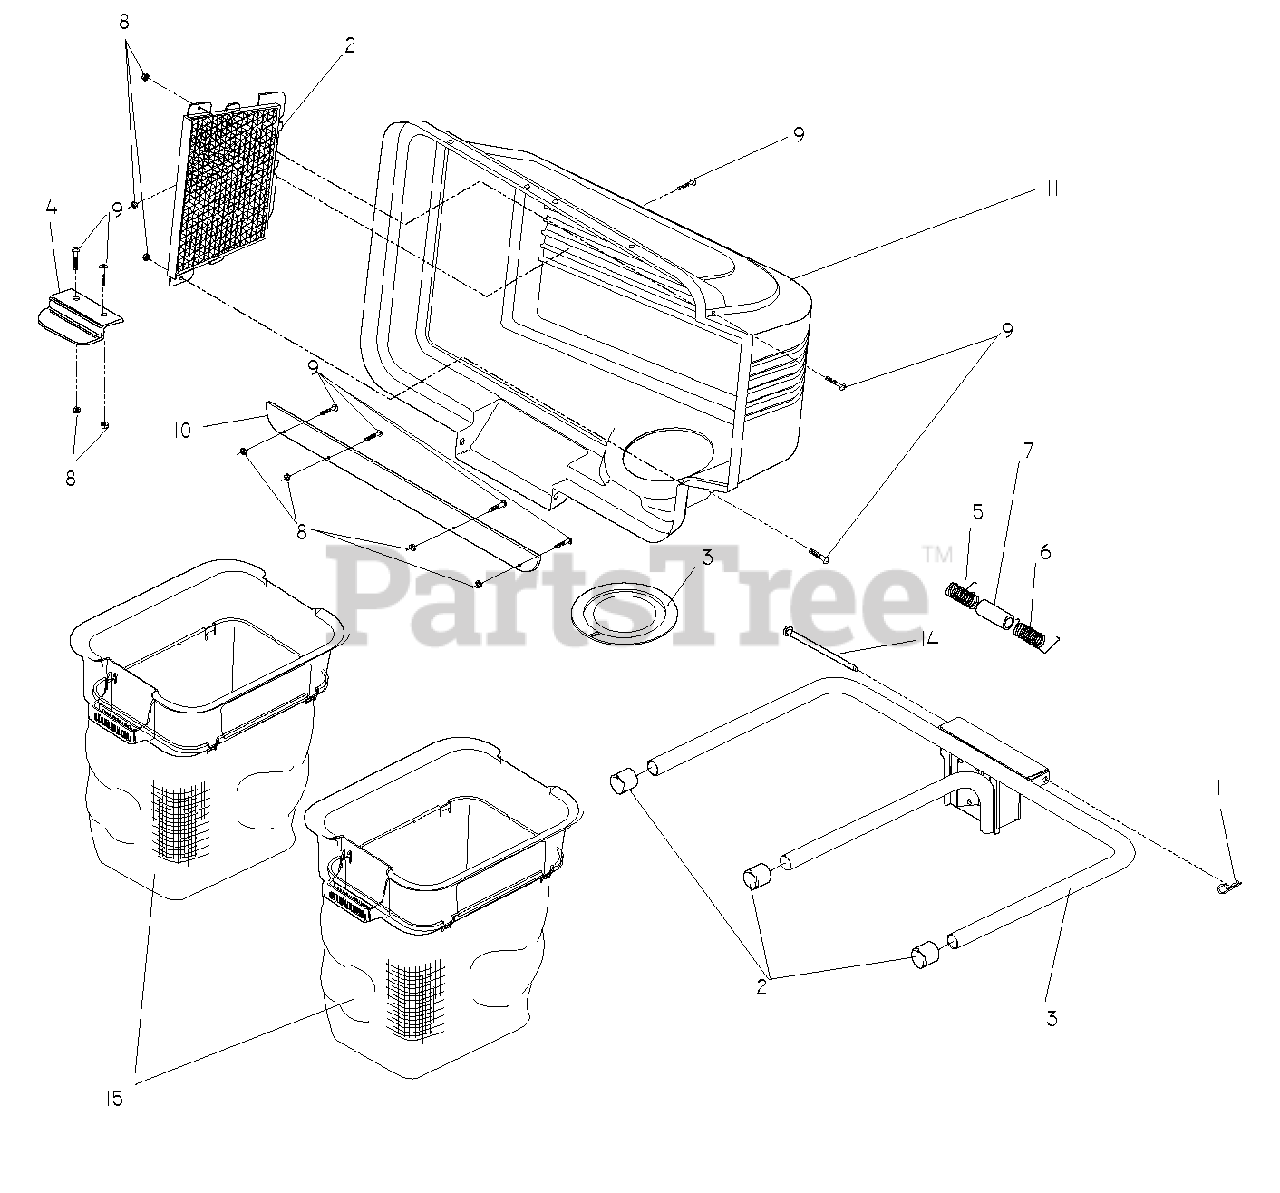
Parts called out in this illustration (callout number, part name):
1	RETAINER-SPRNG RB
2	COVER SCREEN
3	COVER GASKET
4	LATCH CER38
5	SPRING COVER LH
6	SPRING COVER RH
7	SPACER.COVER.BAGGER
8	NUT 10-24 NYLOC
9	SCREW #10 X 1/2 SELF TAPPING
10	STRIP.REINFORCE.BAGGER.2BIN.BL
11	TOP COVER
12	PLUG, TUBING END
13	FRAME ASSEMBLY, 2 BIN
14	BAGGER.HINGE.PIN
15	CONTAINER BAG, SOFT
